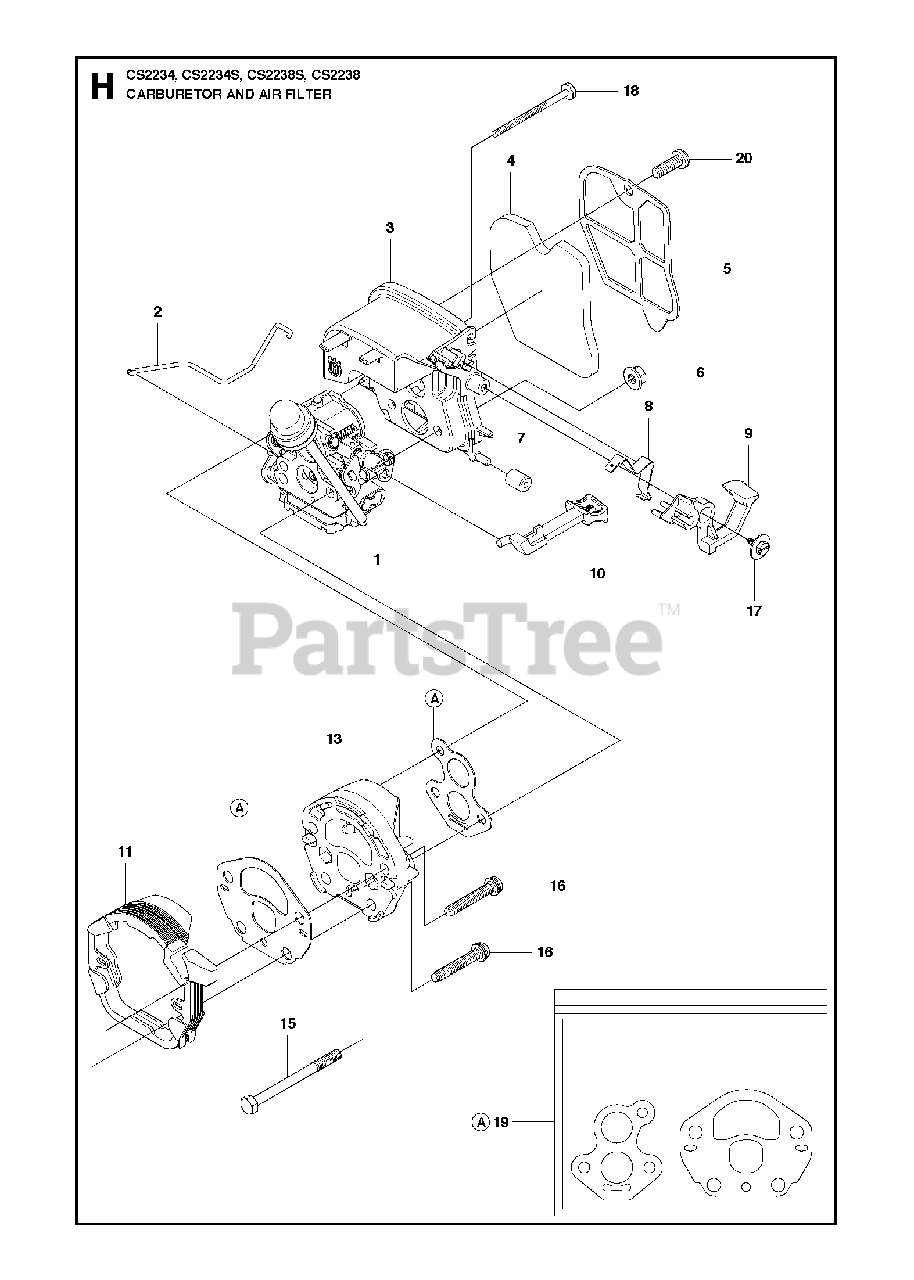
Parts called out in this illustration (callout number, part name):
1	CARBURETOR ZAMA ASSY
2	THROTTLE WIRE
3	FILTER HOUSING
4	AIR FILTER
7	ISOLATOR FILTER HOUSING
9	SWITCH LEVER
10	CHOKE KNOB
11	CARB ADAPTOR SEAL
13	CARB ADAPTOR
15	STUD CARBURETOR
18	TOP STUD - CARBURETOR
19	GASKET KIT
20	SCREW FILTER PLATE
